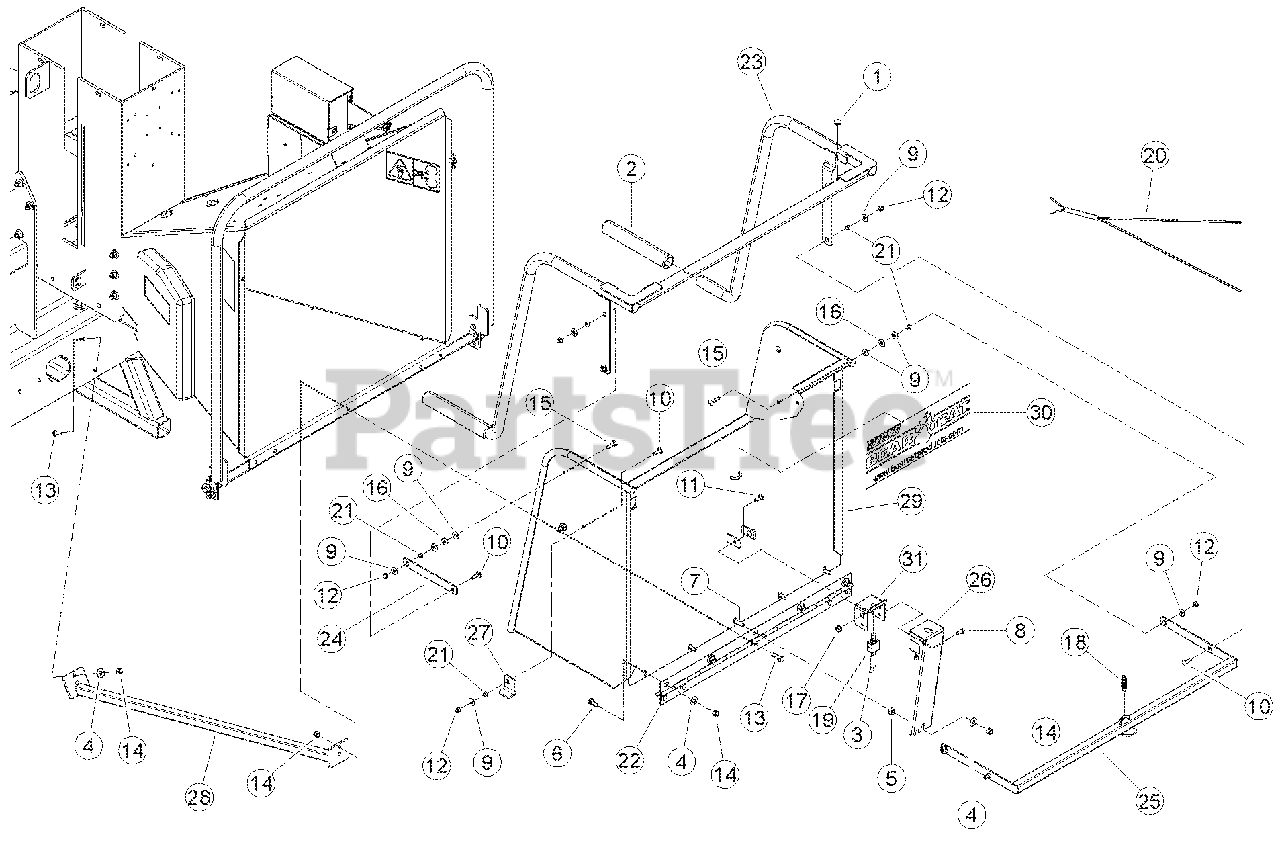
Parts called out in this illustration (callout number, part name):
1	BUMPER, RUBBER
2	GRIP, 1.219 X 10.00
3	CONNECTOR, 1/4 QD MALE
4	WASHER, 3/8 FLAT ZP
5	NUT, 3/8 SERR FLANGE NC ZP
6	BOLT, 3/8 X 1 CRG GR5 NC ZP
7	BOLT, 3/8 X 1-1/2 CRG GR5 NC ZP
8	SCREW, 11/32 X 7/8 HWH AB THREAD ZP
9	WASHER, 5/16 FLAT ZP
10	BOLT, 5/16 X 1 CRG GR5 ZP
11	BOLT,5/16 X 7/8 CRG GR5 NC ZP
12	NUT, 5/16 NE NYLOCK ZP
13	BOLT, 3/8 X 1-1/4 HEX HD GR5 ZP
14	NUT, 3/8 NE NYLOCK ZP
15	BOLT, 5/16 X 1-1/4 CRG GR5 ZP
16	WASHER, 5/16 ID 7/8 OD NYLON FLAT
17	NUT, 5/16-18 NYLOCK-FLANGE
18	SPRING, 1/2 X 2.00 LONG ZP
19	SWITCH, MOMENTARY IP67 NORMALLY ON
20	HARNESS, SAFETY BAR
21	SPACER, IDLER PIVOT
22	HINGE, EXTENSION TRAY
23	WELDMENT, KNEEBAR
24	LINK, PARALLEL
25	WELDMENT, KNEEBAR PIVOT
26	SHIELD, KNEEBAR SWITCH
27	LOCK, SAFETY BAR
28	WELDMENT, CHUTE SUPPORT
29	ASSEMBLY, EXTENSION TRAY, SERVICE PART
30	DECAL, BEARCAT WEB
31	BRACKET, SWITCH
